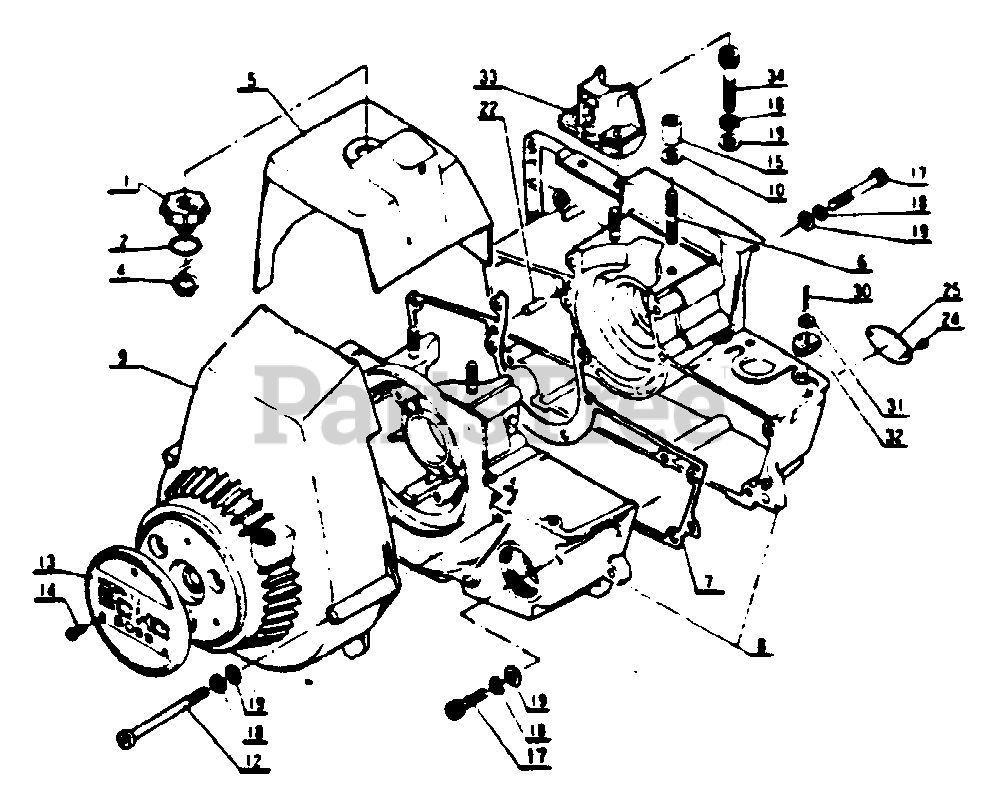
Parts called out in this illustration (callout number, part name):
1	WINGNUT
2	O-RING
4	RING, RETAINING - 11
5	COVER, ENGINE
6	STUD
7	GASKET, CRANKCASE
8	CRANKCASE
9	CASE, STARTER
12	BOLT
13	NAME PLATE
14	SCREW
14	SCREW - 3X6
15	NUT
17	SCREW - 5X20
17	BOLT
18	LOCKWASHER - 5
19	WASHER - 5
22	PIN - LOCATING
24	PLATE, MODEL
25	RIVET
30	PIN, SPLIT -- 2X15
31	WASHER - 6
32	SEAL, FELT
33	BRACKET, HANDLE
34	BOLT - 5X20
34	BOLT
